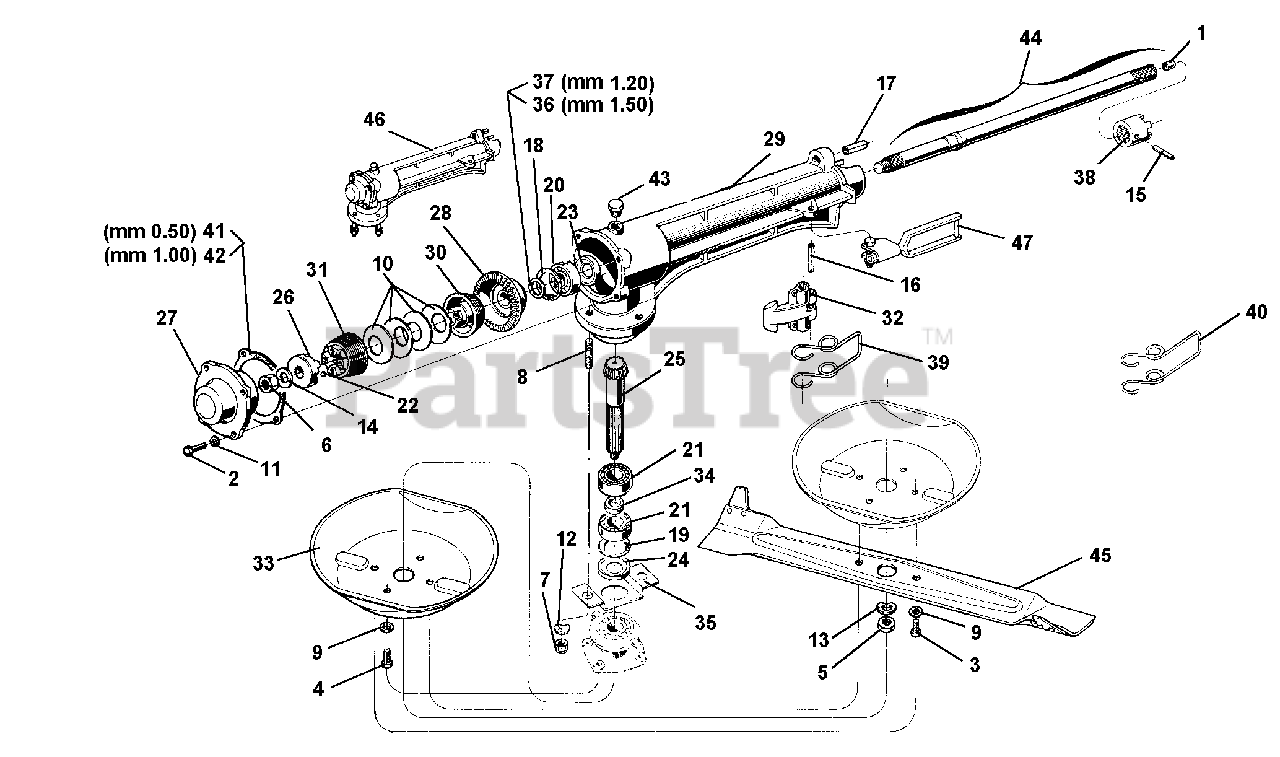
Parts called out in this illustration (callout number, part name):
2	SCREW M6 X 20
3	SCREW M8 X 14
4	SCREW M8 X 12
5	NUT, LOW M12
6	NUT M14 X 1.5
7	NUT SELF-LOCKING, M10 LOW
8	STUD M10 X 37 X 19 X 15 8G
9	SUPER WASHER 8 DIN 6796
10	SPRING 56 X 28 X .5 X 1.5
11	WASHER, LOCK 6.4
12	WASHER, LOCK 10.5
13	WASHER, LOCK 13
14	WASHER, LOCK 15
15	PIN, LOCKING 6 X 40
16	SPIRAL PIN 8 X 40
17	LOCKING PIN 12 X 26
18	CIRCLIP, INTER. D 47
19	CIRCLIP, INTER. D 52
20	BEARING 20 X 47 X 14 6204
21	BEARING 25 X 52 X 15 6205
22	BALL 5/16 RIV RB 7.938
23	OIL SEAL 25 X 40 X 7
24	OIL SEAL 25 X 52 X 7
26	BRAKE COUPLING
28	CONICAL WHEEL
29	HOUSING FOR LAWN MOWER 204
30	STARTER CONE
33	PROTECTION DISC
38	BAR COUPLING
40	LONG SPRING HOOK
43	BREATHER CAP 1/4 GAS
44	PROPELLER SHAFT
45	LAWN MOWER BLADE
46	GEAR ASSEMBLY
47	IMPLEMENT SCREW COUPLING KIT
